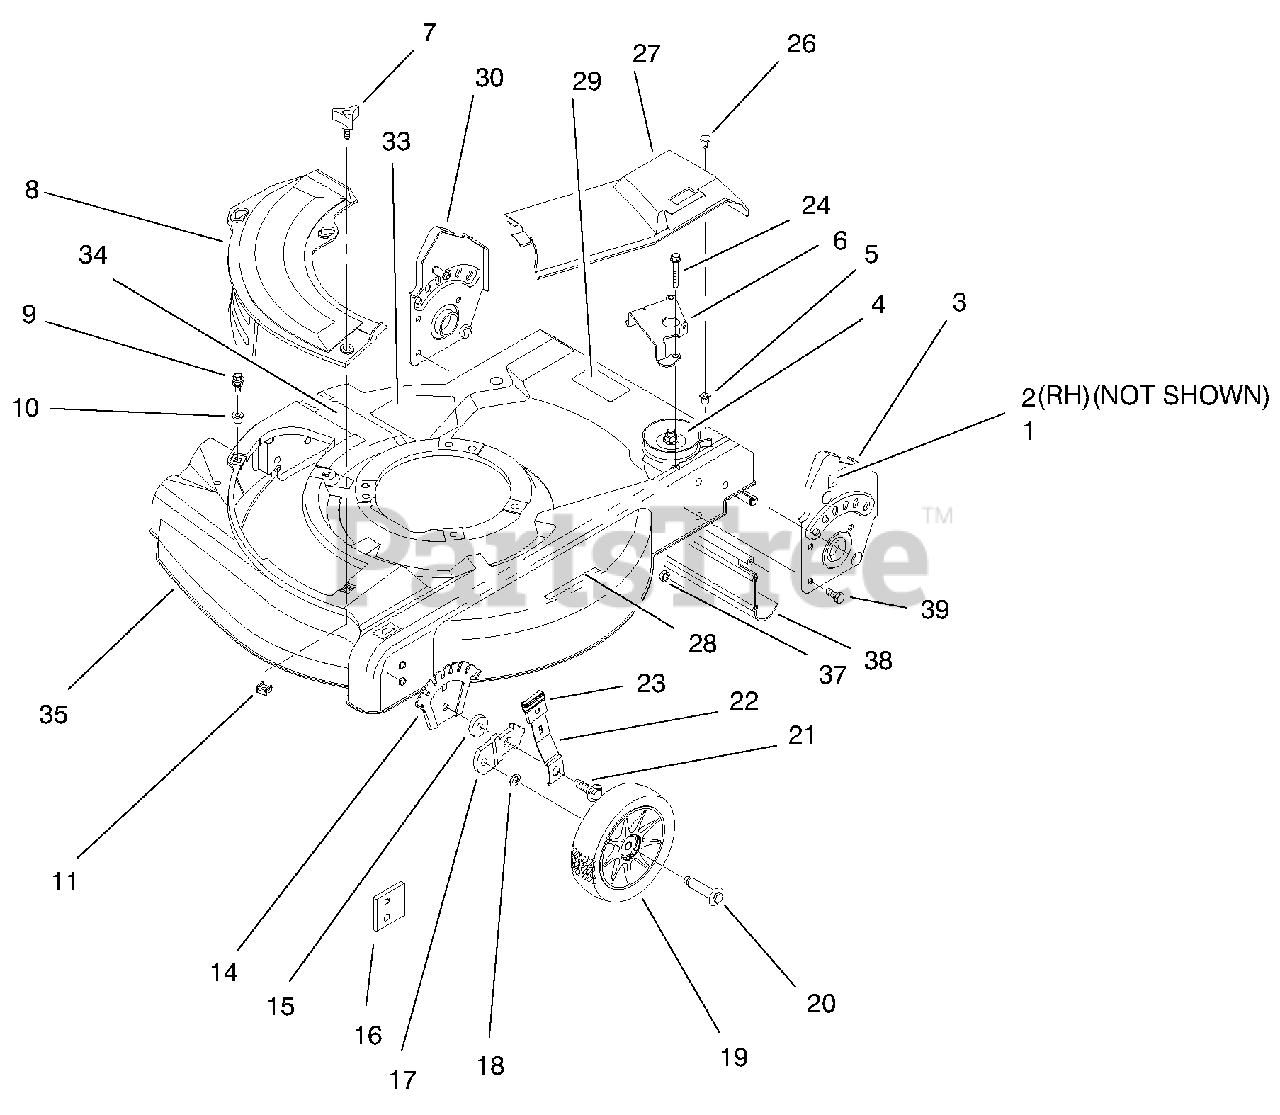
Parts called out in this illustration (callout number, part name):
1	Decal-HOC LH
2	Decal-HOC RH
3	ASM-Handle Bracket
4	ASM-Gear Case
5	Grommet
6	Guide-Transmission
7	Knob-Cover Plate
8	Mulch Plate-21"
9	Screw-Sems
10	Grommet-Plastic
11	Nut-Cage
14	Plate-Height Adjust
16	Plate-Baffle
17	Bracket-Wheel Height Adj
19	ASM-Wheel & Tire 6"
20	Bolt-Shoulder 6" Wheel
21	Bolt-Shoulder
22	Spring Arm-Front
23	Knob-Height Adjust
24	Screw-HH
26	Screw-Phil
27	Cover-Drive
28	Decal-Warning
30	ASM-Handle Bracket
32	Plate-Cover
33	Decal-Danger
34	Decal-Discharge
35	ASM-Housing & Baffle
37	Nut-Lock
38	Shield-Trailing
39	Screw-HH
